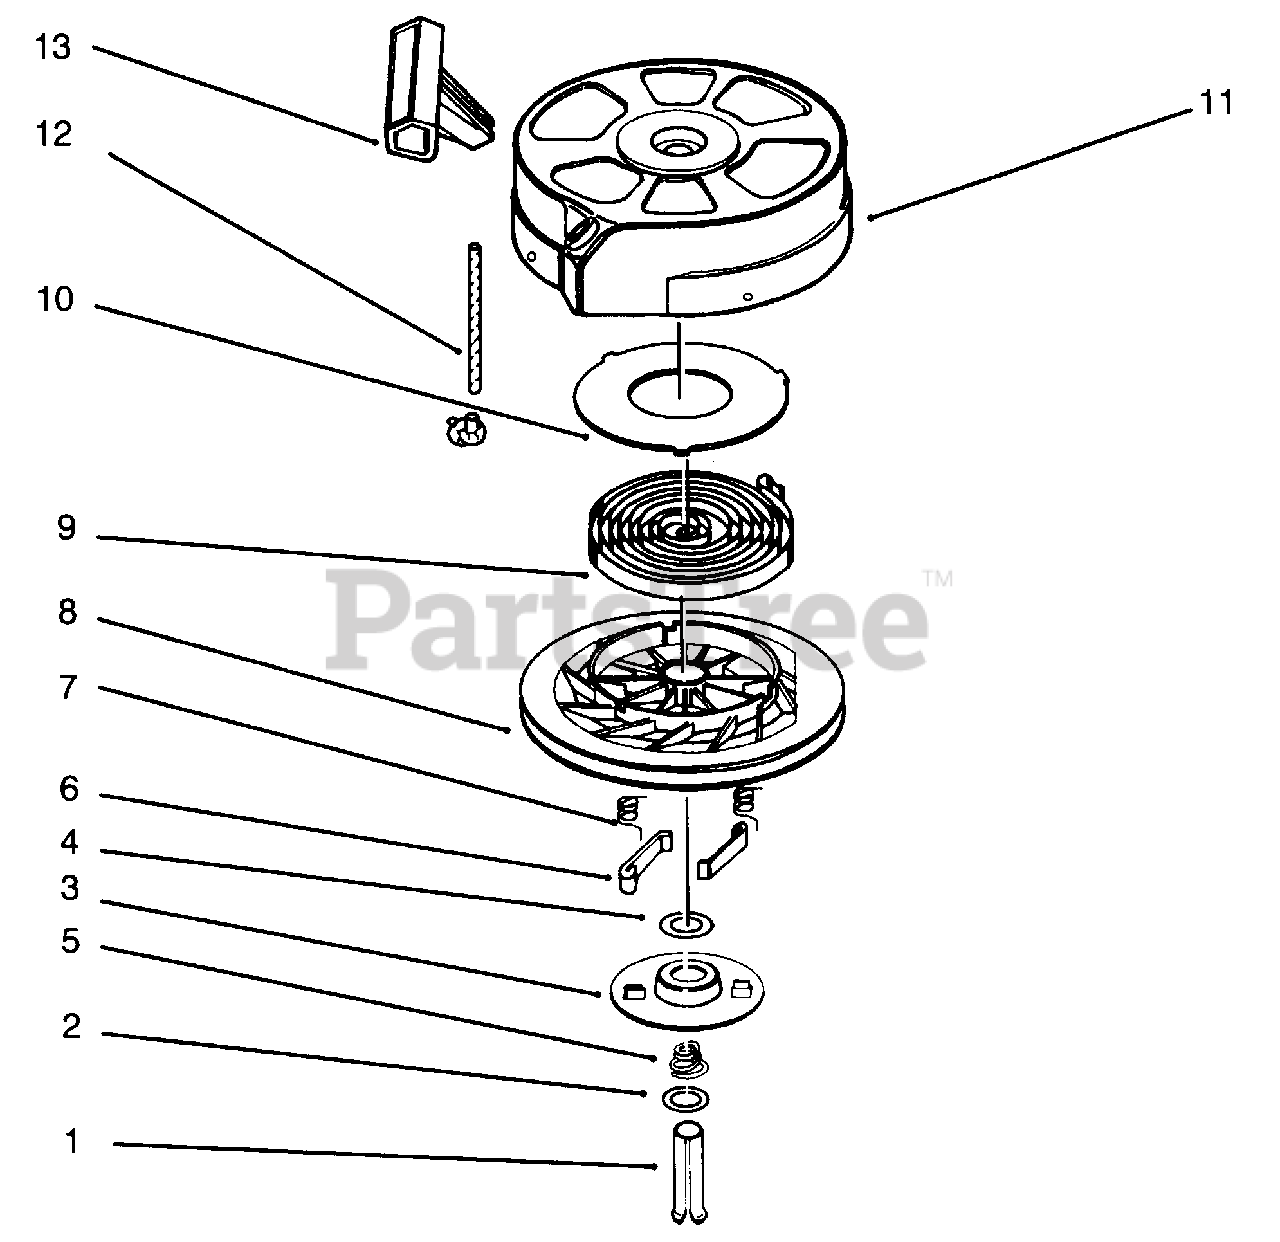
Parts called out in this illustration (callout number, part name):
1	Pin-Spring
3	Retainer
5	Spring-Brake
6	Dog-Starter
7	Spring-Dog
9	Spring-Rewind
10	Cover-Spring
11	Housing Assemble-Starter
12	Rope-Starter
13	Handle Assembly
